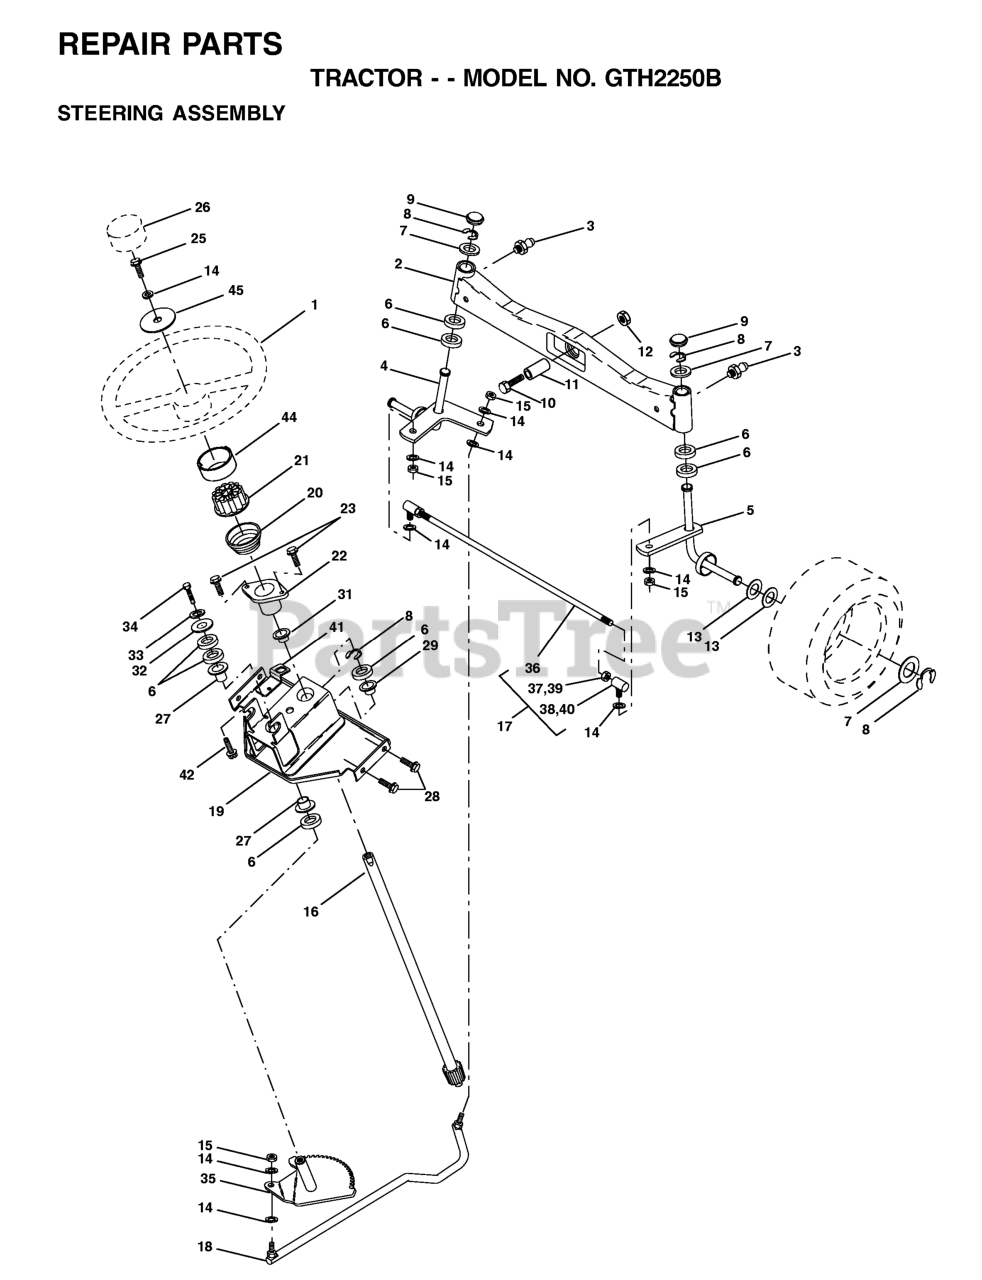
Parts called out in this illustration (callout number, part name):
1	STEERING WHEEL
2	AXLE.FRONT.CAST.MACHINE.W/ZERK
3	ZERK M
4	SPINDLE ASSY LH
5	SPINDLE ASM RH
6	THRUST WASHER
9	CAP.SPINDLE.BLACK
10	Bolt, Hex 5/8 -11 x 2 - 3/4 Gr. 5
11	TUBE, PIVOT AXLE
12	NUT-LOC,FLANGE LT
14	WASHER, LOCK 3/8
15	GRIPCO NUT
16	SHAFT ASM, STEERING
17	ROD ASSY/TIE BALL
18	DRAGLINK, BALL JOINT (3SPG1401
19	SUPPORT ASM., STEERING VGT
20	BOOT, STEERING
21	STEERING WHEEL ADAPTOR
22	BUSHING, STRG. BLK
23	SCREW.TT.#10-32X.5.3/8.FLANGE
26	CAP.WHEEL.STEERING.GREY
27	BRNG T
28	SCREW, 3/8-16X3/4
29	BEARING-FLANGE GT
31	BUSHING.NYLINER.
33	WASHER.LOCK.HVY.HLCL.SPR.5/16
34	BOLT.FIN.HEX.5/16-18X3/4
35	GEAR.ASM.SECTOR.
36	TIE ROD
38	JOINT
41	BRACKET INTERLOCK
42	Screw 5/16-18 x 1/2 Hex, Self Tapping 5/16-18 x 1/2
44	EXTENSION STEERING PREMIUM
45	Washer 13/32 x 1-1/20 x 11 Gauge
